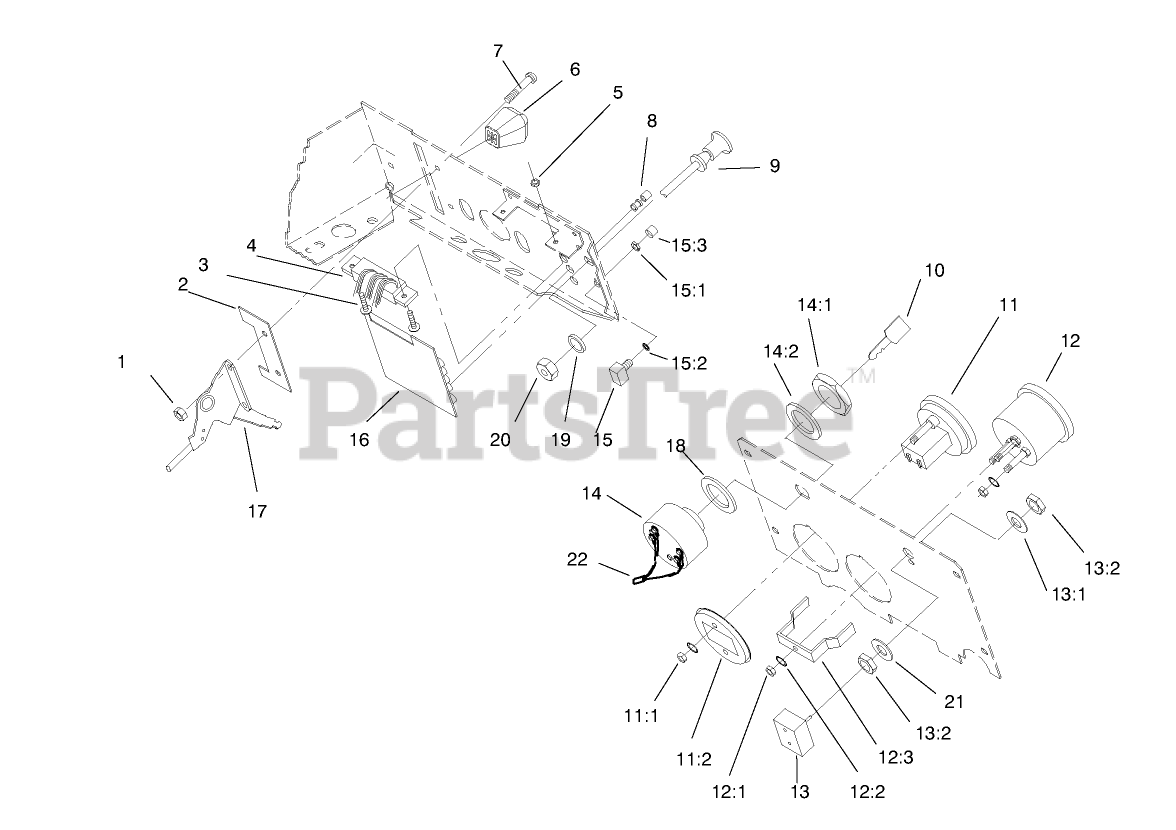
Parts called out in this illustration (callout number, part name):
3	Screw
4	P.C.-BOARD HARNESS
5	NUT-HEX, NYL INS
7	SCREW-PPH
8	ASSY LENS & BUSHING
9	CONTROL CHOKE
10	KEY-IGNITION
11:1	NUT-HEX, KEPS
11:2	Retainer
12	VOLTMETER
12:1	CLAMP-MOUNTING
12:2	WASHER-LOCK / EXT
12:3	NUT-HEX
13	SWITCH-LIGHTS
14	KEY SWITCH ASM
14:2	Washer-Lock
15	SWITCH-PUSH BUTTON
15:1	NUT F/W 116796
15:3	ASSY-TUBE SUCTION
17	CONTROL-THROTTLE
18	WASHER
19	WASHER-FLAT
20	NUT-HEX PALNUT
21	WASHER
